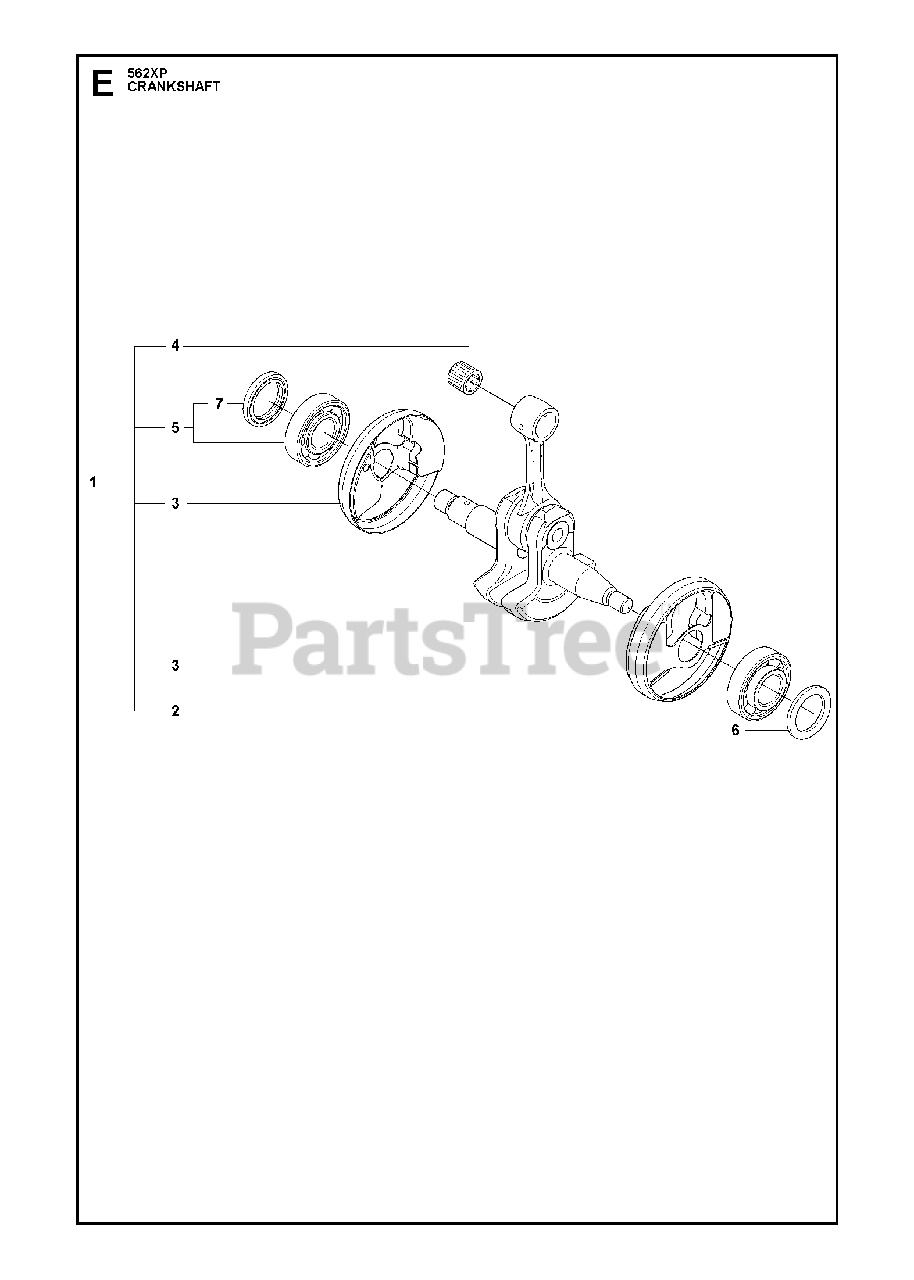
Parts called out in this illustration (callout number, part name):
1	CRANKSHAFT ASSY
2	BALL BEARING
3	CUP
4	NEEDLE BEARING
5	BALL BEARING
6	RADIAL SEAL
7	RADIAL SEAL
